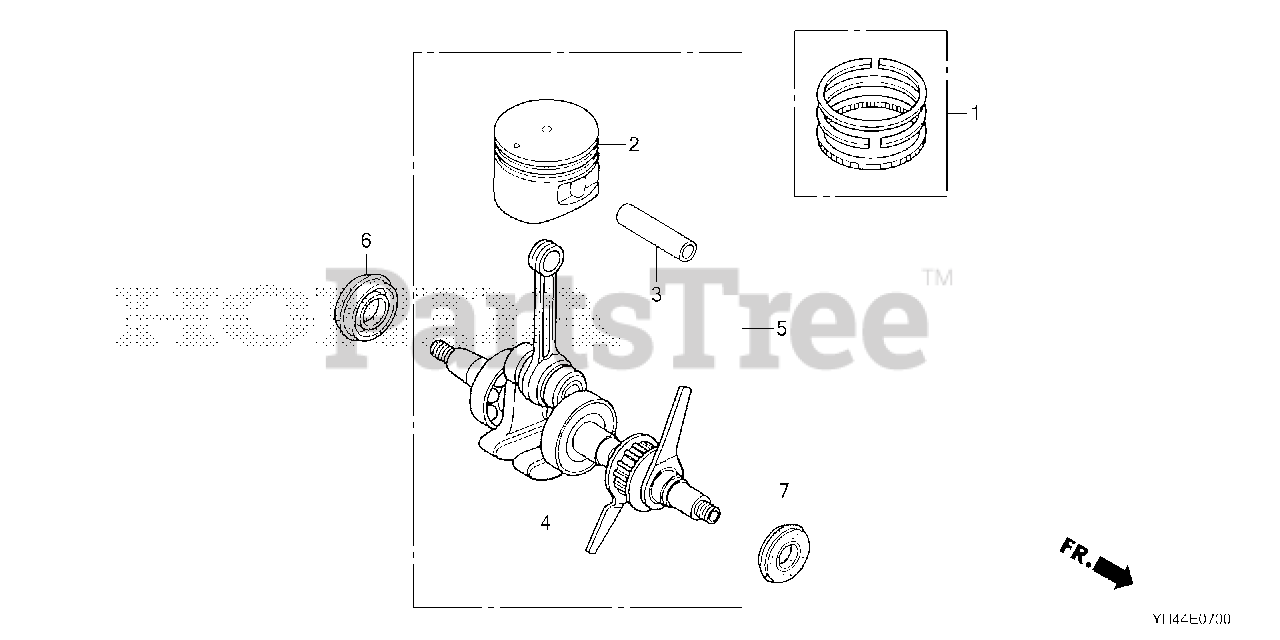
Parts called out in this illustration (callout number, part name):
1	RING SET, PISTON
1	RING SET, PISTON (TPR)
2	PISTON (STD)
3	PIN, PISTON
4	CRANKSHAFT
5	CRANKSHAFT
6	OIL SEAL (12X24X5)
7	OIL SEAL (10X20X5)
